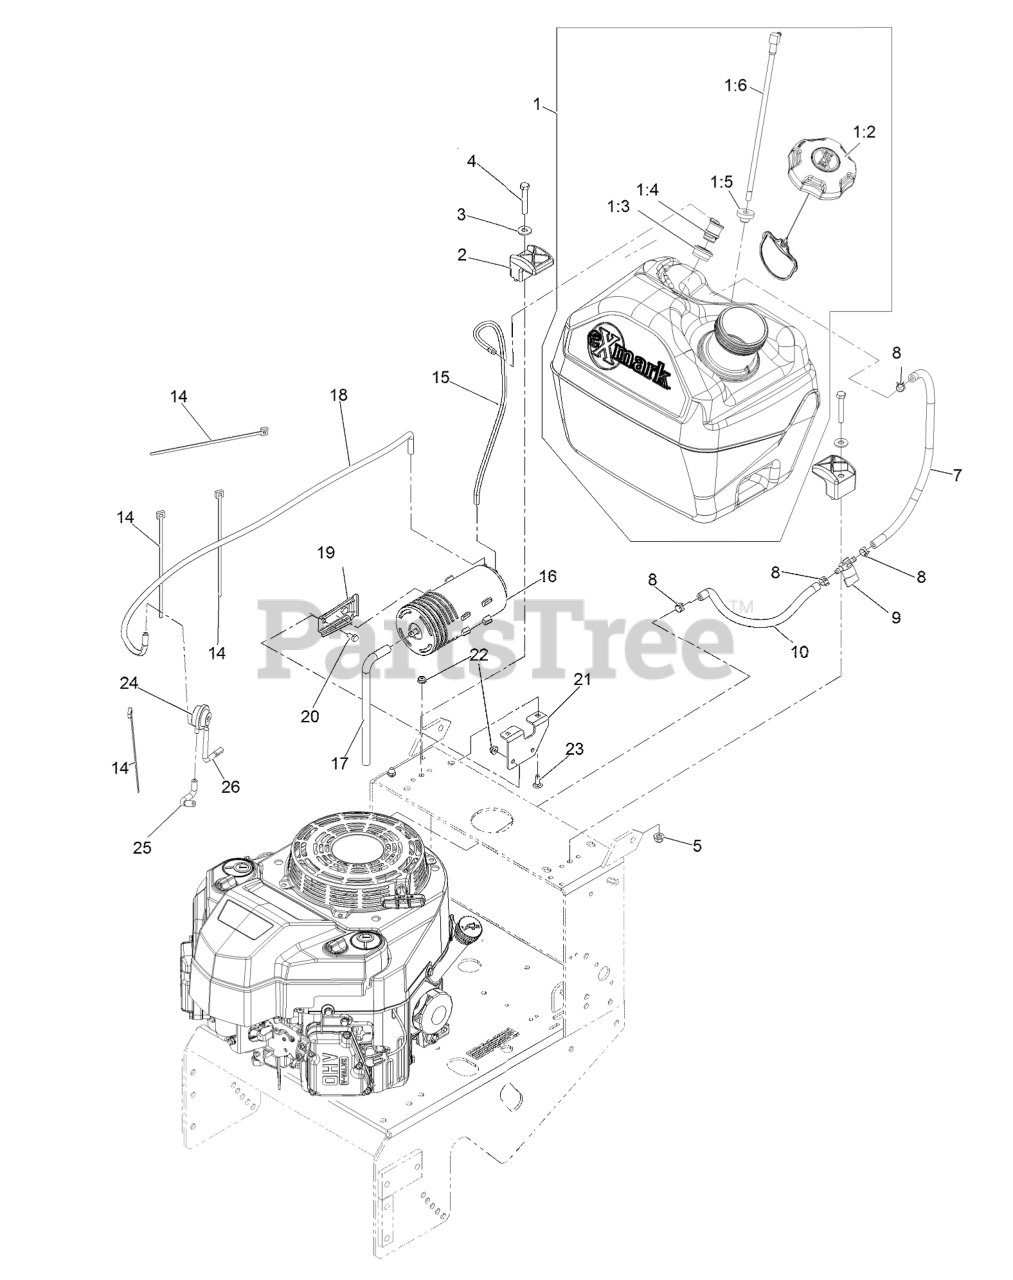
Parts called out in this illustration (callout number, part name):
1	ASM, FUEL TANK
1:3	GROMMET
1:4	VALVE-VENT, FUEL
1:5	FITTING-FUEL, BULKHEAD
3	WASHER-FLAT
4	SCREW-HH
5	NUT-HF, NI
7	HOSE-FUEL
8	CLAMP-HOSE
9	VALVE-FUEL
10	HOSE-FUEL
14	TIE-PLASTIC
15	HOSE-VENT
16	CANISTER-CARBON, 800CC
17	HOSE-VENT, CANISTER
18	HOSE-VENT, FORMED
19	BRACKET-CANISTER, CARBON
20	SCREW-HH
21	BRACKET-CANISTER, CARBON
23	BOLT-CARR
24	VALVE-CONTROL, VACUUM
25	HOSE-VENT, FORMED
26	HOSE-VENT, FORMED
